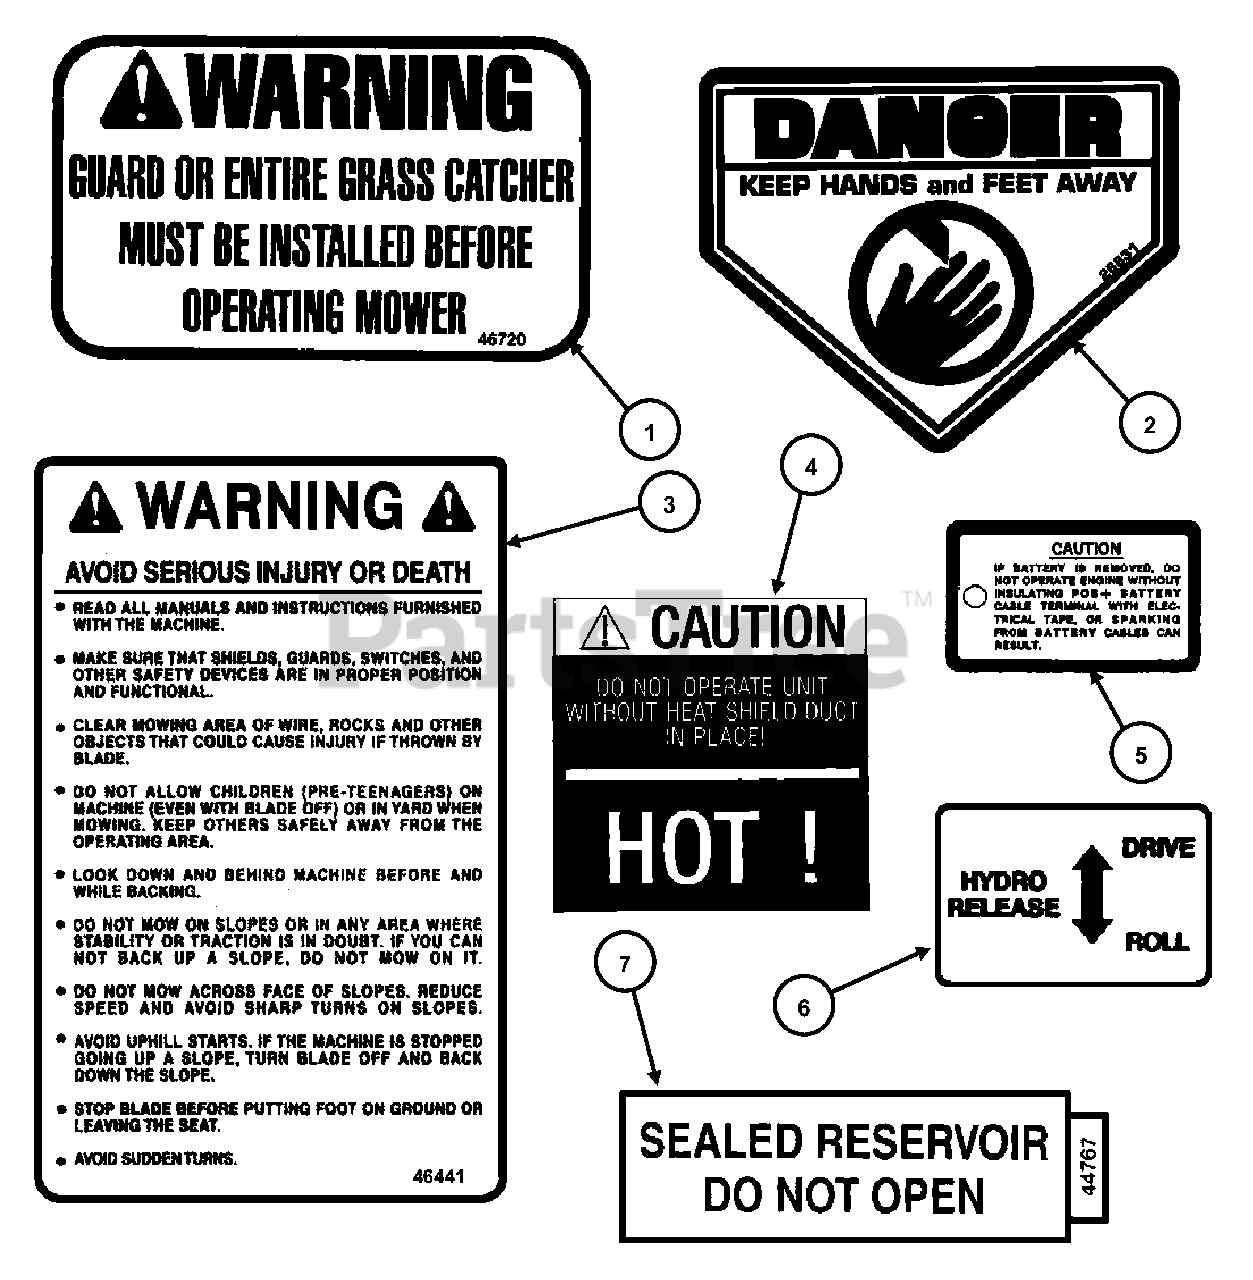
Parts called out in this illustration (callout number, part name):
1	DECAL, Warning Chute Deflector
2	DECAL, CPSC (similar to 1-3010)
3	DECAL, Safety Instructions
4	DECAL, Heat Shield
5	DECAL, Caution Tag
6	DECAL, Hydro Release
7	DECAL, Hydro Reservoir
